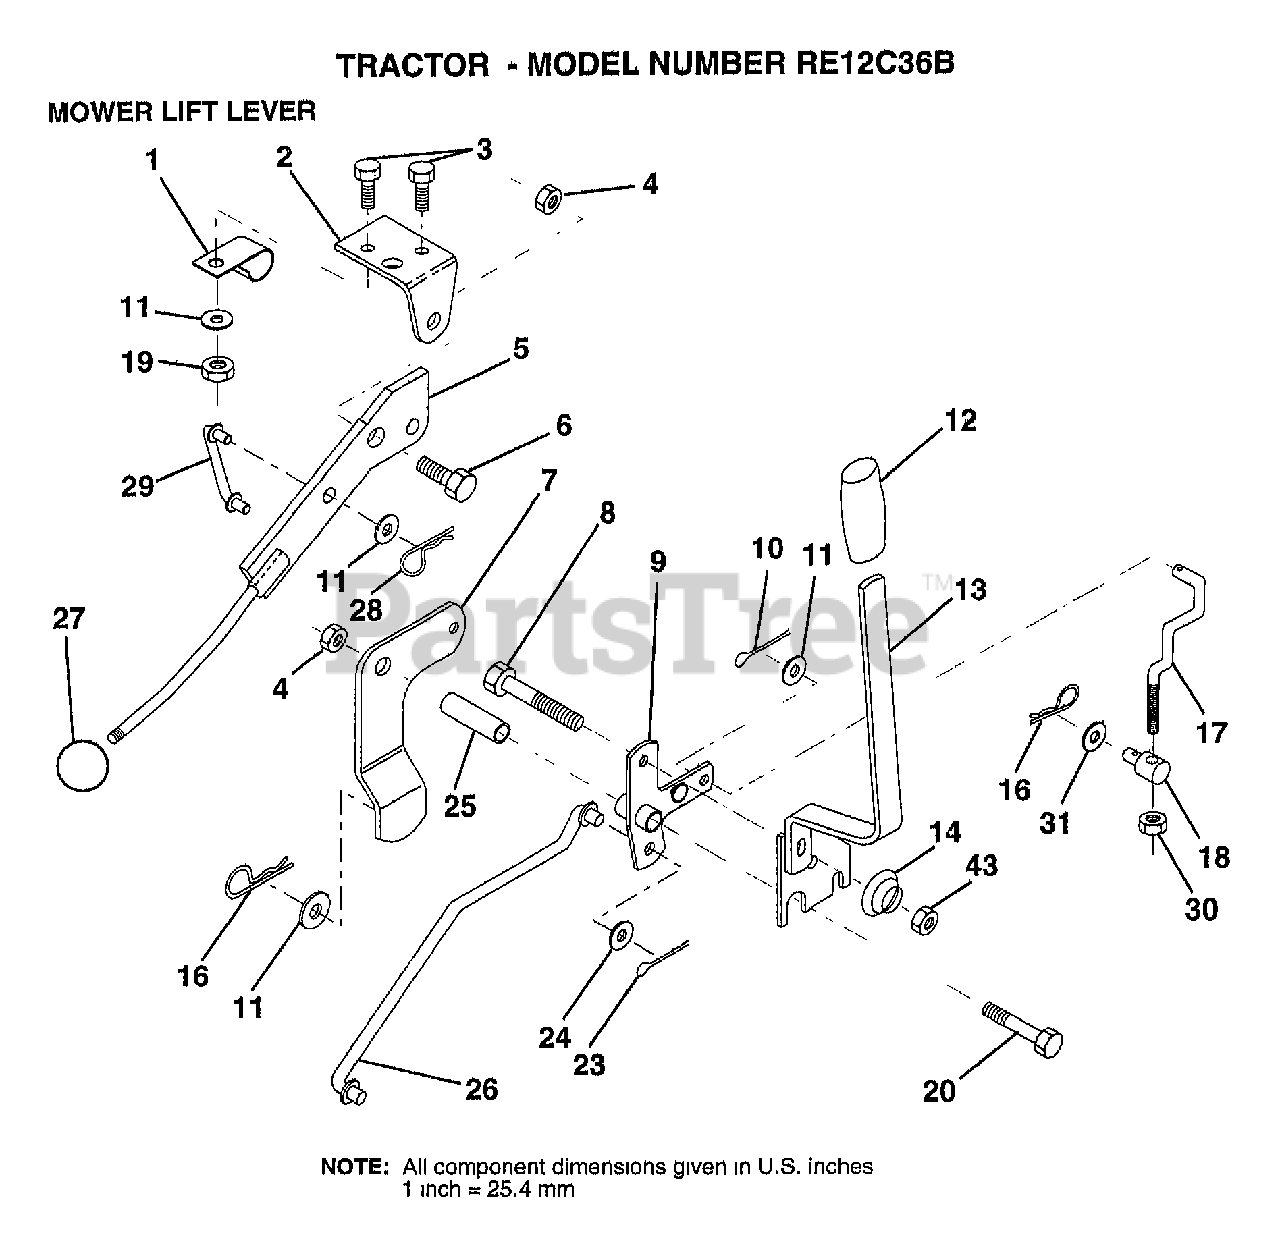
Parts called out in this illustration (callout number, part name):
1	"CLIP,INSULATOR"
2	BRKT CLUTCH
3	BOLT HXHD FIN
5	LEVER.ASM.CLUTCH
6	"BOLT, SHOULDER LT"
7	MWR CLUTCH ARM AS
8	BOLT
9	"BELLCRANK,LIFT"
10	COTTER PIN
11	WASHER
13	HANDLE.ASM.LIFT
14	SPRING COMPRESSIO
16	SPRING.RETAINER
17	"LINK,LIFT FRT"
18	TRUNION ADJ
19	NUT HXKEP 1/4X20
20	BOLT
23	PIN COTTER 1/8
25	TUBE SPACER
26	ROD LIFT MOWER
27	KNOB T(3/8 HOLE)
28	RETAINER M
29	CLUTCH LINK
30	NUT
31	WASHER
